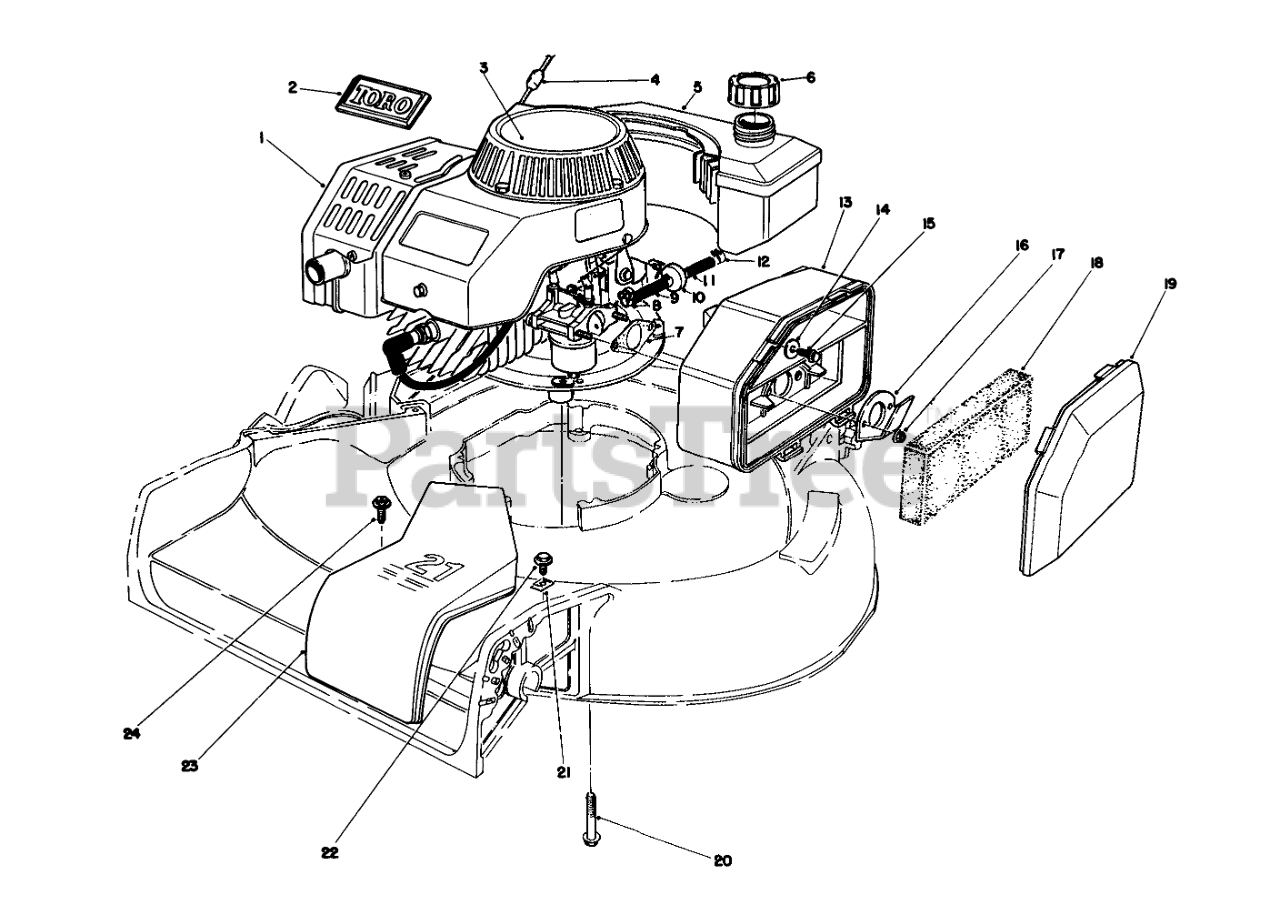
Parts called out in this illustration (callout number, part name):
1	Engine
2	TORO LOGO PLT
3	DECAL
5	FUEL TANK ASM
6	GAS CAP ASM
7	GASKET-AIR CLEANER
8	FUEL LINE CLAMP
9	HOSE-FUEL
10	FILTER-FUEL
11	HOSE-FUEL
12	CLAMP-FUEL LINE
13	AIR CLEANER
14	WASHER-FLAT
15	SCREW-HH
16	SPIT BACK DEFLECTOR
17	NUT-LOCK
18	FILTER
19	AIR CLEANER COVER
20	SCREW-HHF, WHIZ
21	CLAMP-CABLE
22	SCREW-HWHTF
23	BELT COVER 21" S D
24	SCREW
